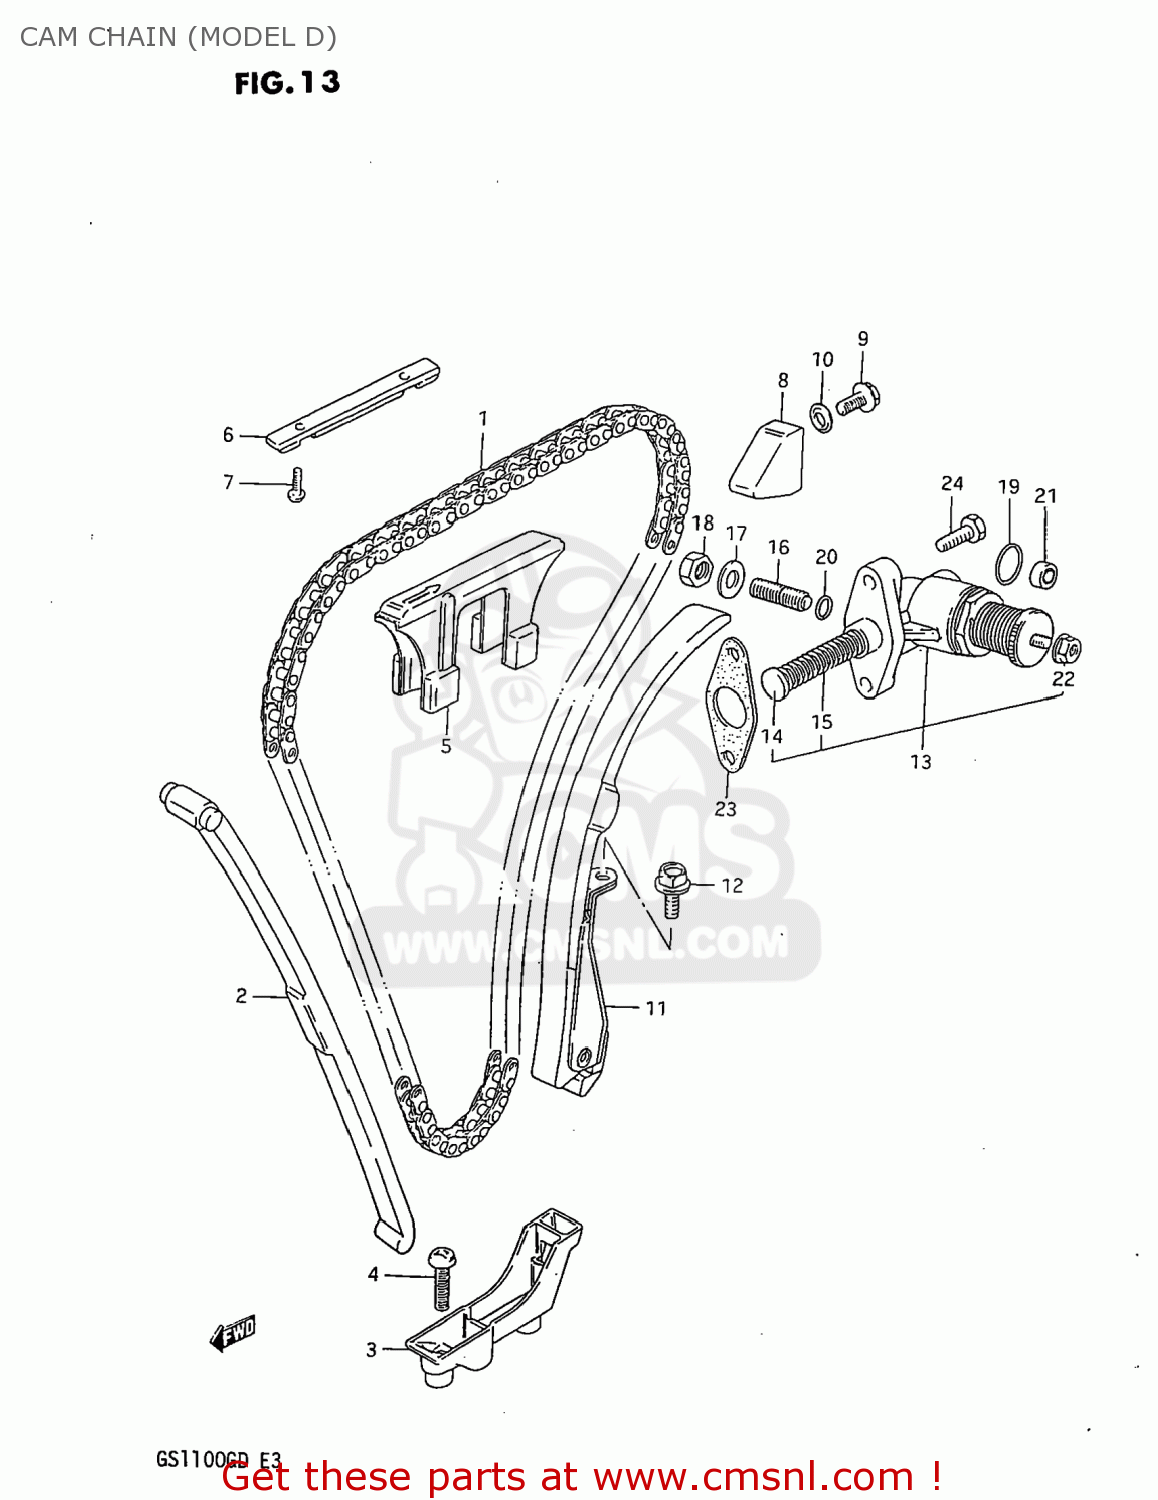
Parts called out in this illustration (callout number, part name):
1	CHAIN,CAMSHAFT DRIVE
2	GUIDE,CAM CHAIN NO.1
3	HOLDER,CAM CHAIN GUIDE
4	SCREW
5	GUIDE,CAM CHAIN NO.2
6	GUIDE,CAM CHAIN
7	SCREW
8	GUIDE,CAM CHAIN
9	BOLT 6X12
10	GASKET (NAS)
11	TENSIONER,CAM CHAIN
12	BOLT
13	ADJUSTER ASSEMBLY,TENSIONER
14	ROD,PUSH
15	SPRING
16	SCREW,TENSIONER ADJUST
17	WASHER,8.5X16X
18	NUT
19	O-RING
20	O-RING
21	OIL SEAL
22	NUT
23	GASKET,TENSIONER ADJUSTER (MCA)
24	SCREW
